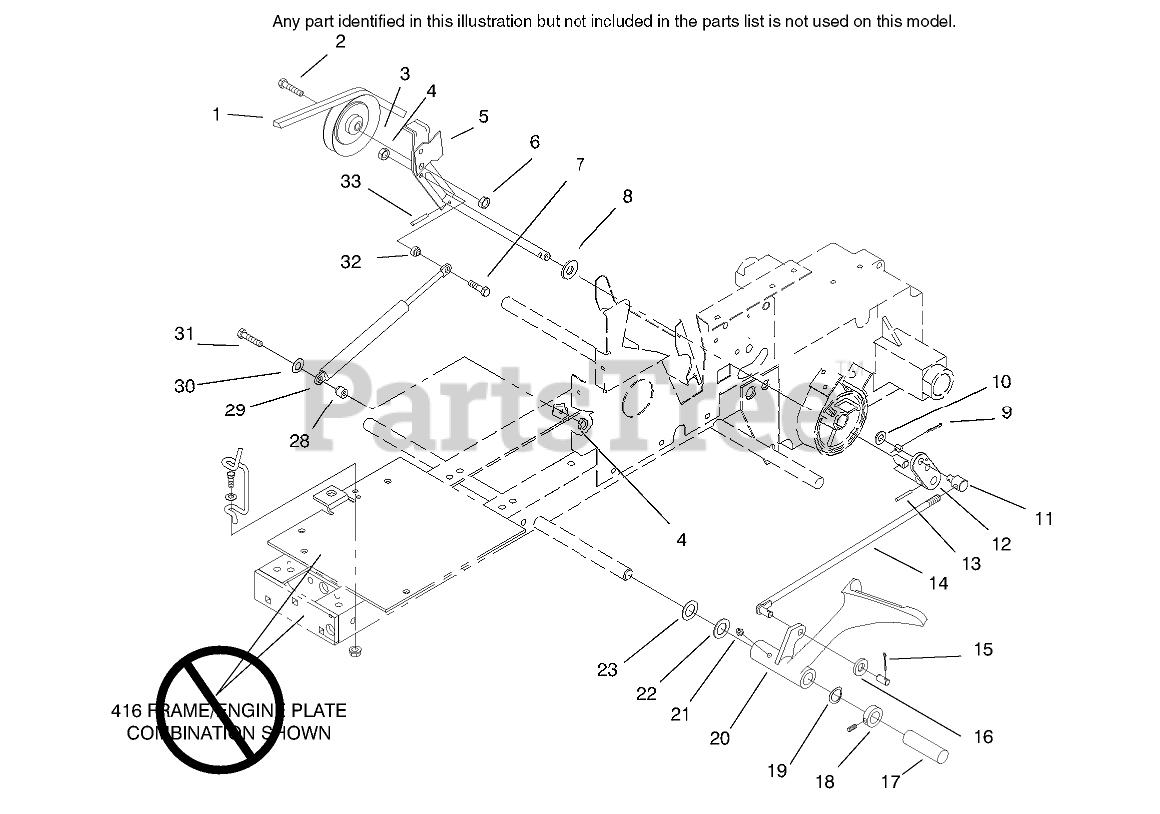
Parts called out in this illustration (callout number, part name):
1	BELT-V IN
2	BOLT-SPECIAL HEX
3	PULLEY-IDLER
4	NUT-LOCK, NI
5	ASM-Clutch Idler Arm
6	NUT-HEX
7	Capscrew
8	SHIM-WASHER
9	PIN-COTTER
10	WASHER-FLAT
11	TRUNNION
12	Arm-Clutch Rod
13	PIN-SPIROL
14	ROD AND GUIDE ASM
15	PIN-COTTER
16	WASHER-NYLON
17	SLEEVE-PROTECTIVE
18	COLLAR
19	WASHER-BOWED
20	PEDAL-BRAKE, CLUTCH
21	FITTING-GREASE
22	WASHER
23	WASHER
28	SPACER-SHOULDER-.400
29	ASS'Y-GAS SPRING
30	WASHER-FLAT
31	SCREW-HH
32	SPACER-SHOULDER-.200
33	PIN-SPIROL
